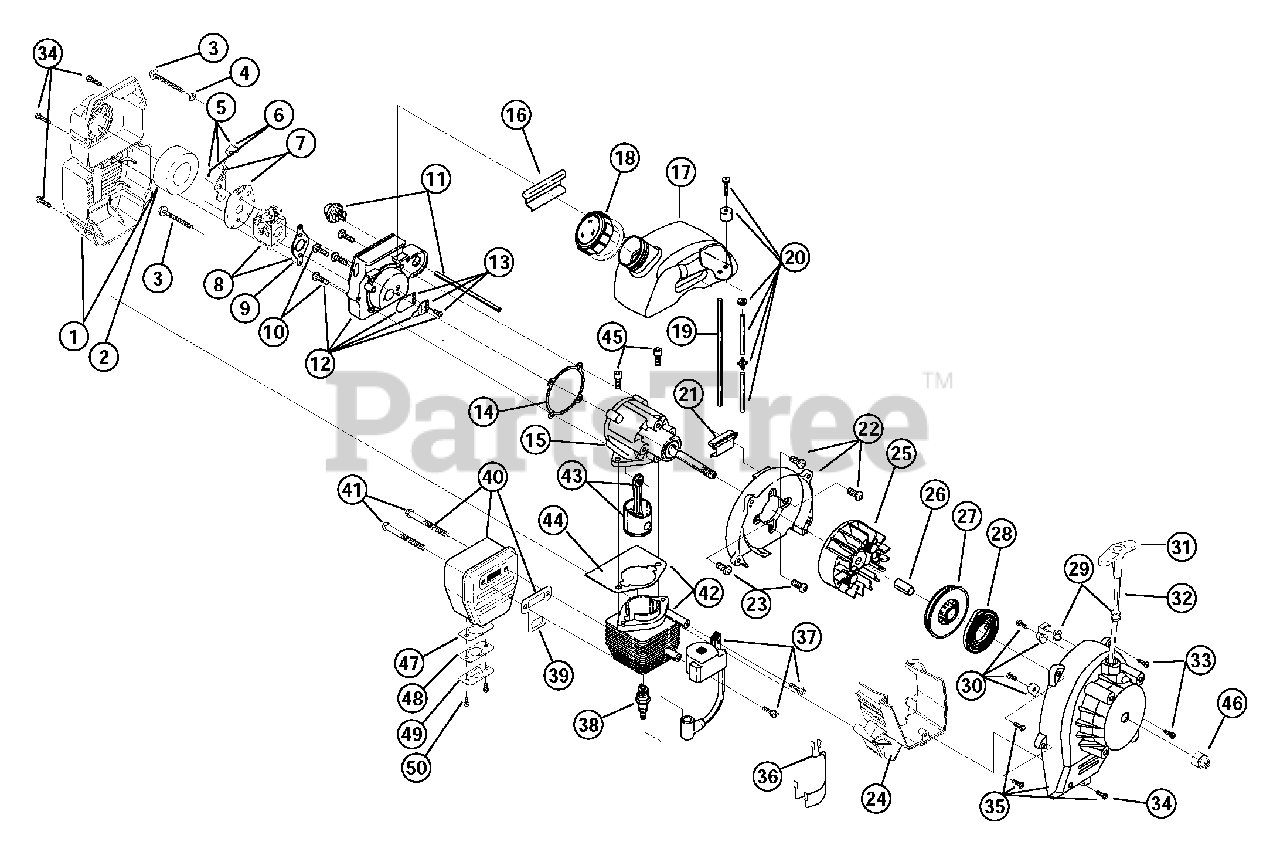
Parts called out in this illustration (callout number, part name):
1	Air Cleaner/Muffler Cover Assembly
2	Air Cleaner Filter
3	Carburetor Mounting Screw
4	Wavey Washer
5	Choke Lever Assembly
6	Choke Knob and Screw
7	Choke Lever and Plate
8	Carburetor Assembly
9	Carburetor Gasket
10	Carb Mount Screw
11	Primer and Hose Assembly
12	Carb Mount Assembly
13	Reed Assembly
14	Carburetor Mount Gasket
15	Crank Case Service Assembly
16	Rear Mounting Pad
17	Fuel Tank Assembly
18	Fuel Cap Assembly
19	Fuel Return Line
20	Fuel Line Assembly
21	Front Mounting Pad
22	Shroud Assembly
23	Shroud Screw
24	Shroud Extension
25	Flywheel Assembly
27	Recoil Pulley Assembly
28	Recoil Spring
29	Rope Guide
30	Pulley Retainer Assembly
31	Pull Handle
33	Housing Screw
34	Cover Screw
35	Starter Housing Assembly
36	Wire Lead Assembly
37	Module Assembly
38	Spark Plug
39	Exhaust Gasket
40	Muffler Assembly
41	Muffler Mounting Bolts
42	Cylinder Assembly
43	Piston and Rod Assembly
44	Cylinder Gasket
45	Cylinder Bolt
46	Crankshaft Extension
47	Spark Arrestor
48	Spark Arrestor Plate
49	Spark Arrestor Hood
50	Spark Arrestor Screws
